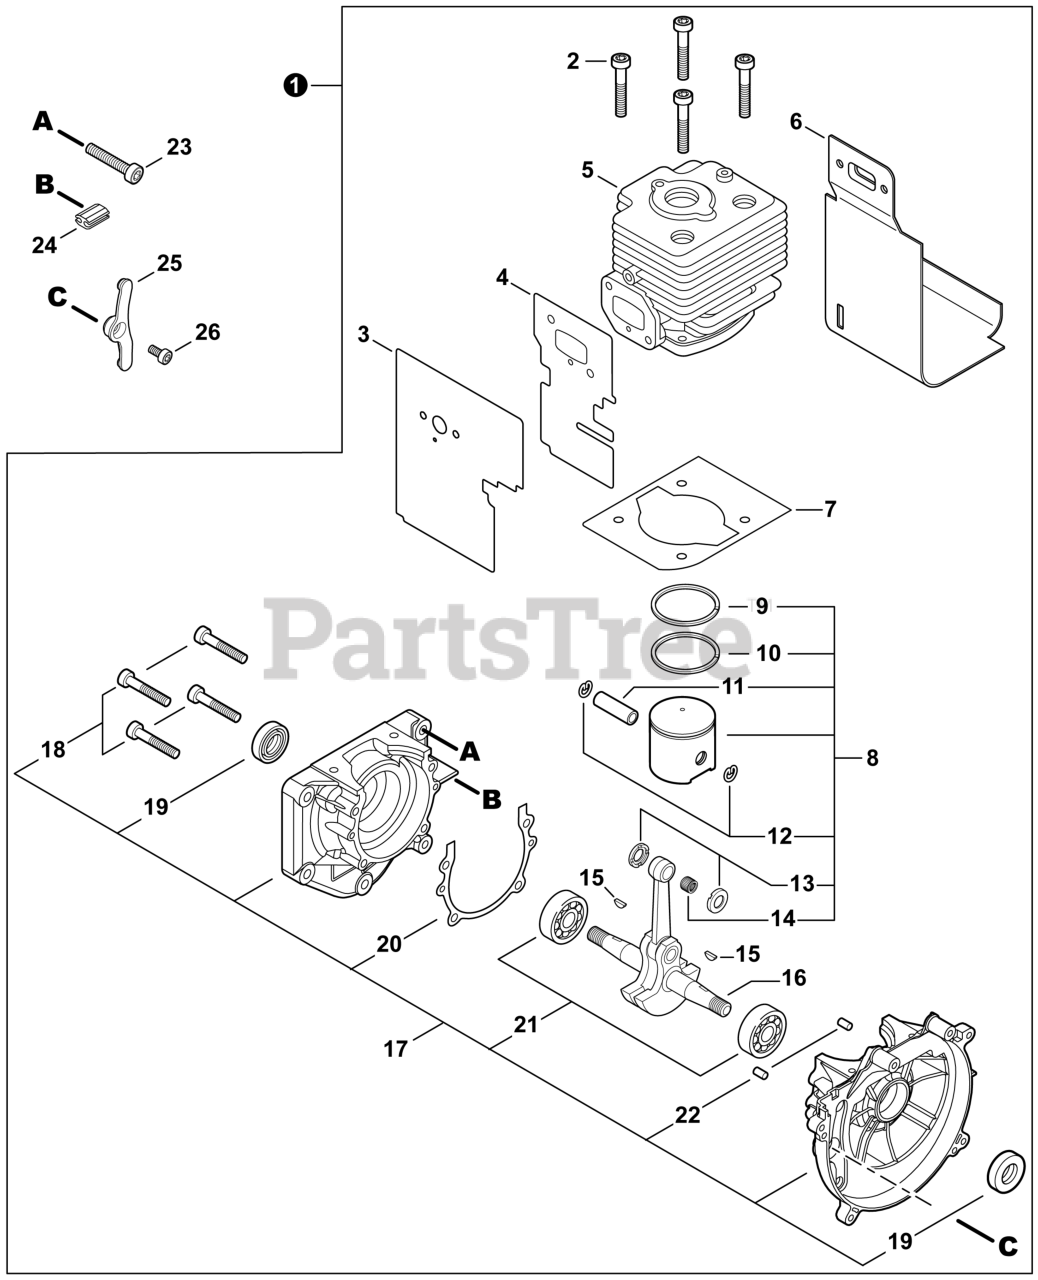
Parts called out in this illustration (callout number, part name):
1	SHORT BLOCK
2	BOLT, TORX 5x25
3	HEAT SHIELD, INTAKE
4	HEAT SHIELD, INTAKE
5	CYLINDER
6	HEAT SHIELD, EXHAUST
7	GASKET, CYLINDER
8	PISTON KIT
9	RING, PISTON
10	RING, PISTON
11	PIN, PISTON
12	RING, SNAP 8
13	WASHER, THRUST
14	BEARING, NEEDLE 10
15	KEY, WOODRUFF 3x14
16	CRANKSHAFT ASSY
17	CRANKCASE KIT
18	BOLT, TORX 5x30
19	SEAL, OIL 15
20	GASKET, CRANKCASE
21	BEARING, BALL 6302
22	PIN, LOCATING 4x8
23	BOLT, TORX 6x30
24	COVER, DUST
25	COVER, DUST
26	BOLT, TORX 5x10
